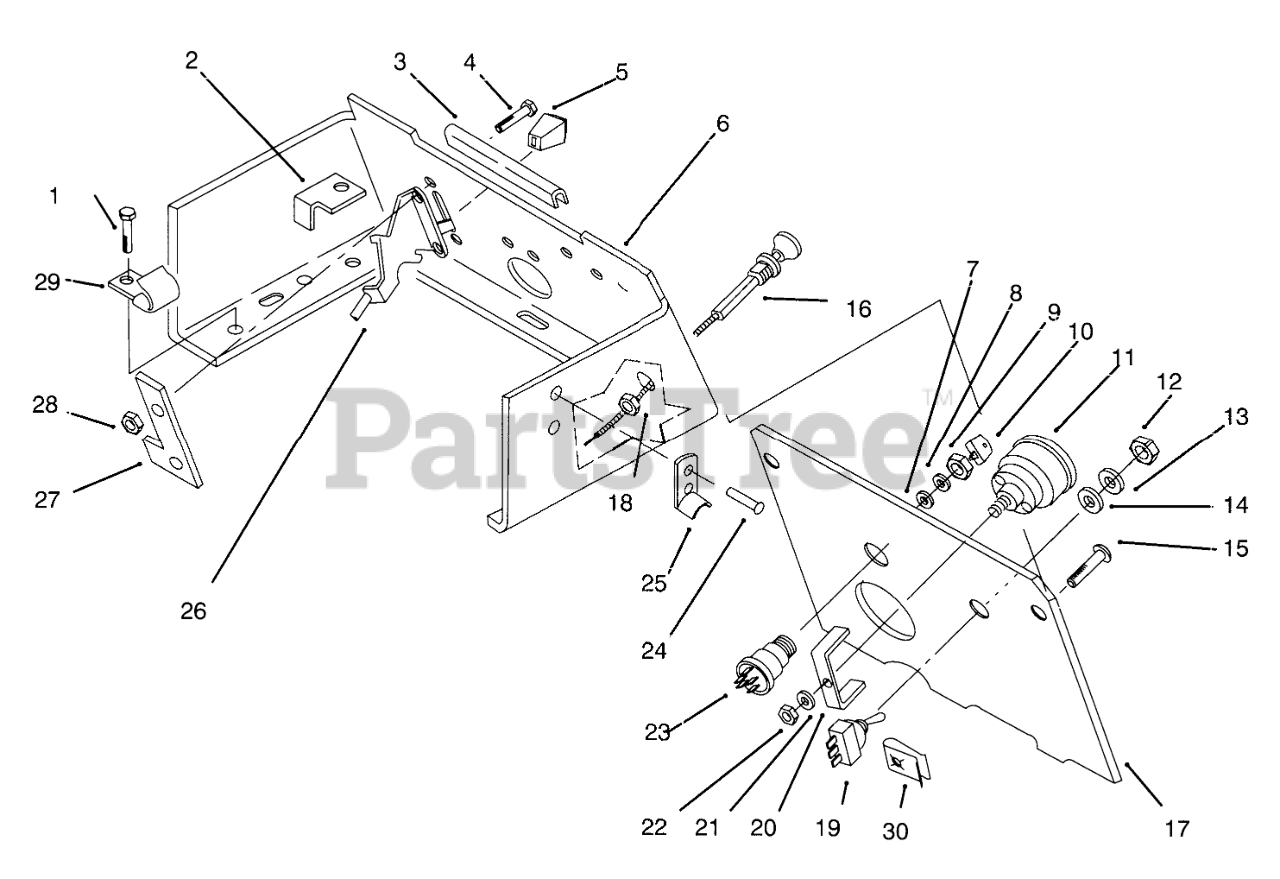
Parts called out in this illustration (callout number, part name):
1	SCREW
2	STOP-PTO
3	EDGING-CONSOLE
4	Screw
6	CONSOLE B
7	Washer
8	LOCKWASHER
10	KEY-IGNITION
11	Meter-Hour(Incl. Ref.# 20-22)
13	TAB-WASHER
14	Washer
15	Screw
16	CONTROL CHOKE
17	PLATE HOODSTAND B
18	NUT-HEX PALNUT
19	Switch-Light(Incl. Ref. #12-14)
20	CLAMP-HOUR METER
21	WASHER-LOCK
22	NUT-HEX
23	KEY SWITCH ASM
24	POPRIVET 1/8X 1/8 BK
25	KEEPER-LATCH
26	CONTROL-THROTTLE
27	Washer
28	Nut
29	J-CLIP
30	CLIP
